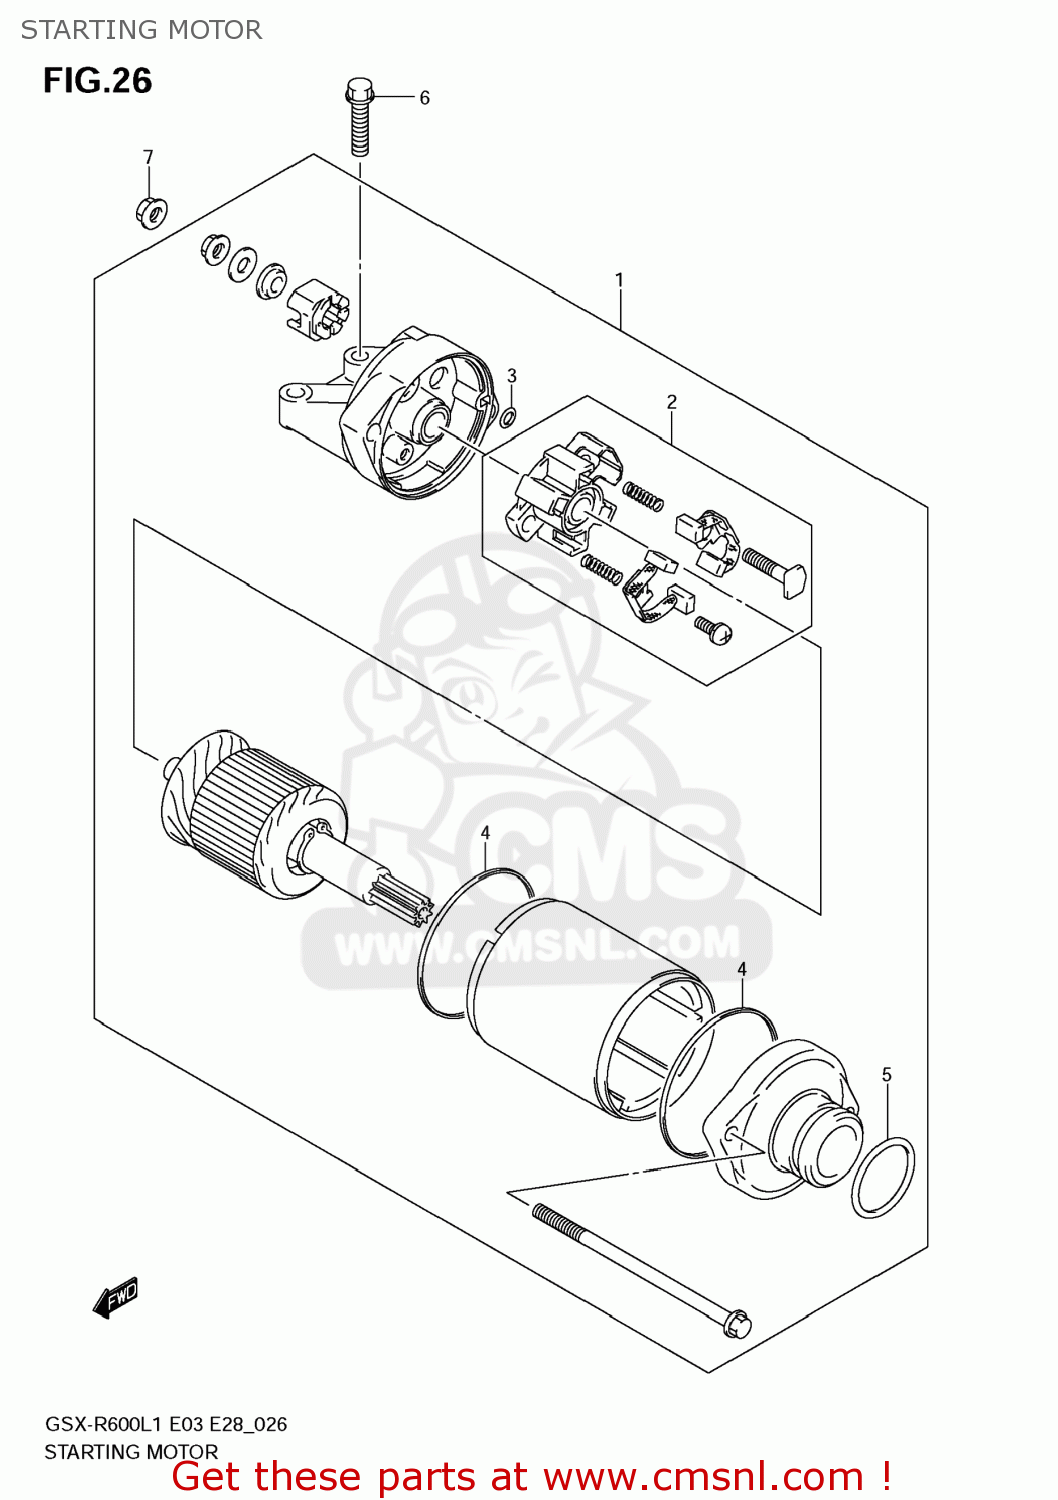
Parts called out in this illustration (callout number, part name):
1	MOTOR ASSY.STARTING
2	BRUSH HOLDER SET
3	O RING
4	SQUARE RING
5	O RING
6	BOLT(6X25)
7	NUT
